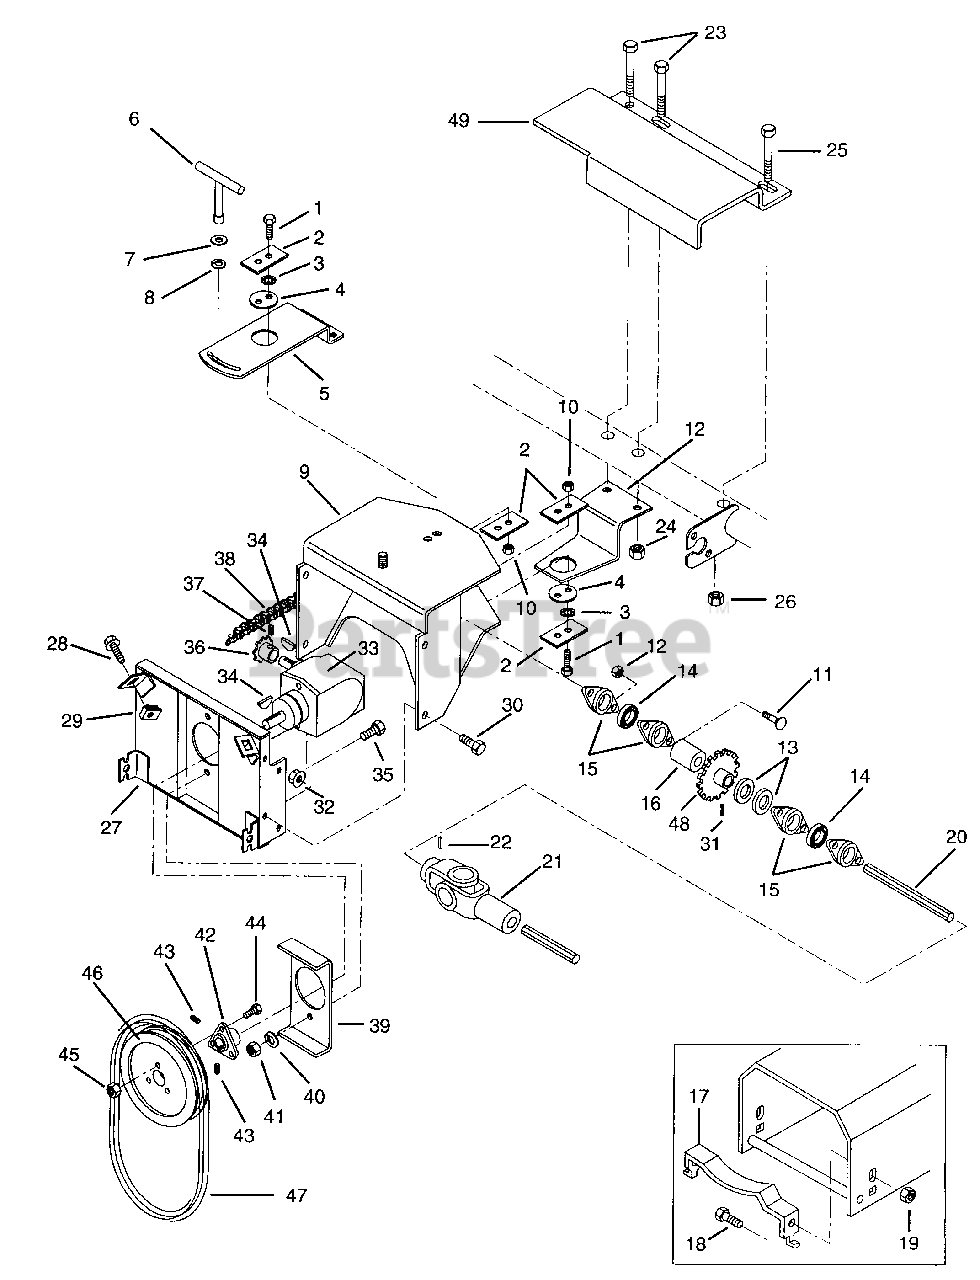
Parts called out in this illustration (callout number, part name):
1	INSTSHT, GRAB LIGHT 701-147M
2	RETAINER
3	@WSHR-LK-EXT.326X.599X.031YWZC
4	PIVOT CENTER
5	PLATE, TOP MOUNT
6	T-LOCK HANDLE
7	@WSHR-FL-STL.38X.875X.083 YWZC
8	@WSHR-LK .38X.094 REG YWZC
9	ADAPTER FRAME
10	NUT-LK-TOP .312-18 GR C PL
11	@BLT-RDHDSQNK .31-18X.75 G5YZ
12	PLATE, BOTTOM MOUNT
13	WSHR-FL-STL 1.010X1.505X.062YZ
14	BRG-BALL .884HEXX52MMX1.07
15	BEARING FLANGE
16	SPACER 1.006X1.307X.500
17	BELT RETAINER
18	@BLT-HEX .25-20X.50 GR5 YWZC
19	@NUT-LK-CTR .25-20 YWZC
21	JOINT, UNIVERSAL
22	PIN-ROLL .188X1.50
23	@BLT-HEX .38-16X3.25 GR5 YWZC
24	@NUT-LK-CTR .38-16 YWZC
25	@BLT-HEX .38-16X3.00 GR5 YWZC
26	@NUT-LK-CTR .38-16 YWZC
27	MOUNTING PLATE
28	BLT-SERHFWH .38-16X.75 YWZC
29	NUT-RETNR .38-16 TINRMAN
30	@BLT-HEX .38-16X.75 GR5 YWZC
31	PIN-ROLL .188X1.75
32	NUT-LK-FLG .375-16 GR A PL
33	GEAR BOX ASSEMBLY
34	KEY-WDRF .188X.75X.313 SAE 9
35	@BLT-HEX .38-16X1.25 GR5 YWZC
36	SPROCKET
37	SCR-SET .25-20X.38 SKHCUPNL OH
38	CHAIN
39	STIFFENER PLATE
40	@WSHR-LK .38X.094 REG YWZC
41	@NUT-HEX .38-16 YWZC
42	HUB ASSEMBLY
43	SCR-SET .32-18X.38 SKHCUPNL OH
44	BLT-SERRDHD SL .31-18X.75 YZ
45	NUT-FLG. .312-18 PL
46	PLY-V 9.0 X 1.25 3BLT
47	V-BELT, 4L-RAW EDGE
48	SPROCKET
49	SHAFT GUARD
